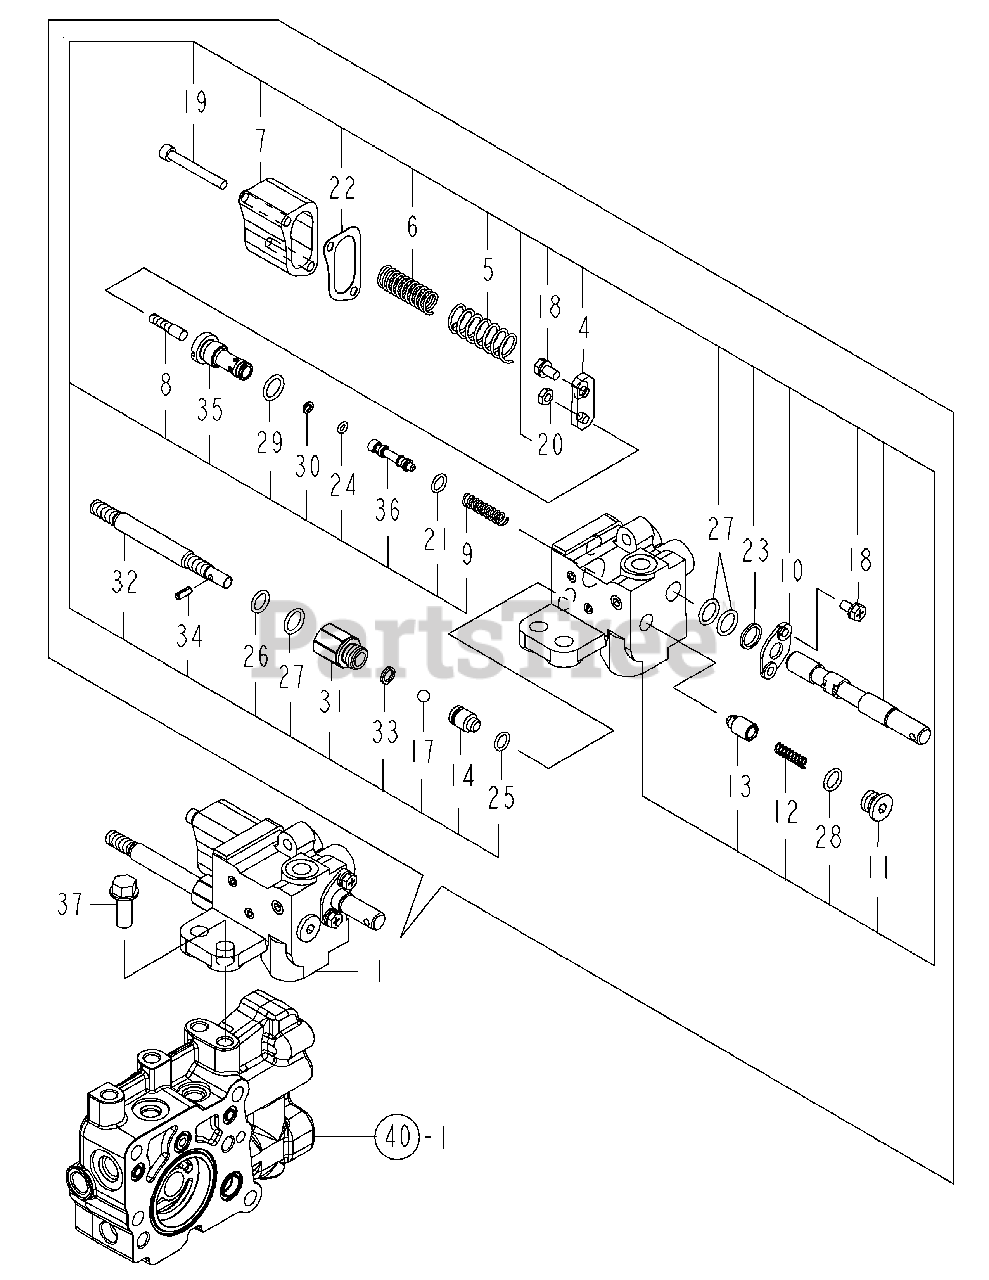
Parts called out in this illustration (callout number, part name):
1	VALVE ASSY, LIFT
4	PLATE,LIFT VALVE
5	SPLING,LIFT VALVE
6	SPLING,LIFT VALVE
7	COVER,LIFT VALVE
8	PUSH ROD,LIFT VALVE
9	SPRING,MECHA,VALVE
10	PLATE,LIFT VALVE
11	PLUG,LIFT VALVE
12	SPRING,LIFT VALVE
13	POPPET,CHECK,VALVE
14	PLUNGER,LIFT VALVE
21	ORING,LIFT VALVE
22	PACKING,LIFT VALVE
23	DUST SEAL,LIFT VALVE
24	PACKING, P 5.0
25	PACKING, P 10.0
26	PACKING, P 12.0
27	PACKING, P 14.0
28	PACKING, P 12.0
29	PACKING, P 14.0
30	RING,BACKUP T2 P 5
31	GUIDE,LIFT VALVE
32	SHAFT,LIFT VALVE
33	WASHER,LIFT VALVE
34	PIN, 4.0A X 12
35	SLEEVE,MECHA,VALVE
36	SPOOL,MECHA,VALVE
50	SEAL KIT,LIFT VALVE
51	STOP BOLT KIT,VALVE
52	MECHAVALVE KIT,VALVE
